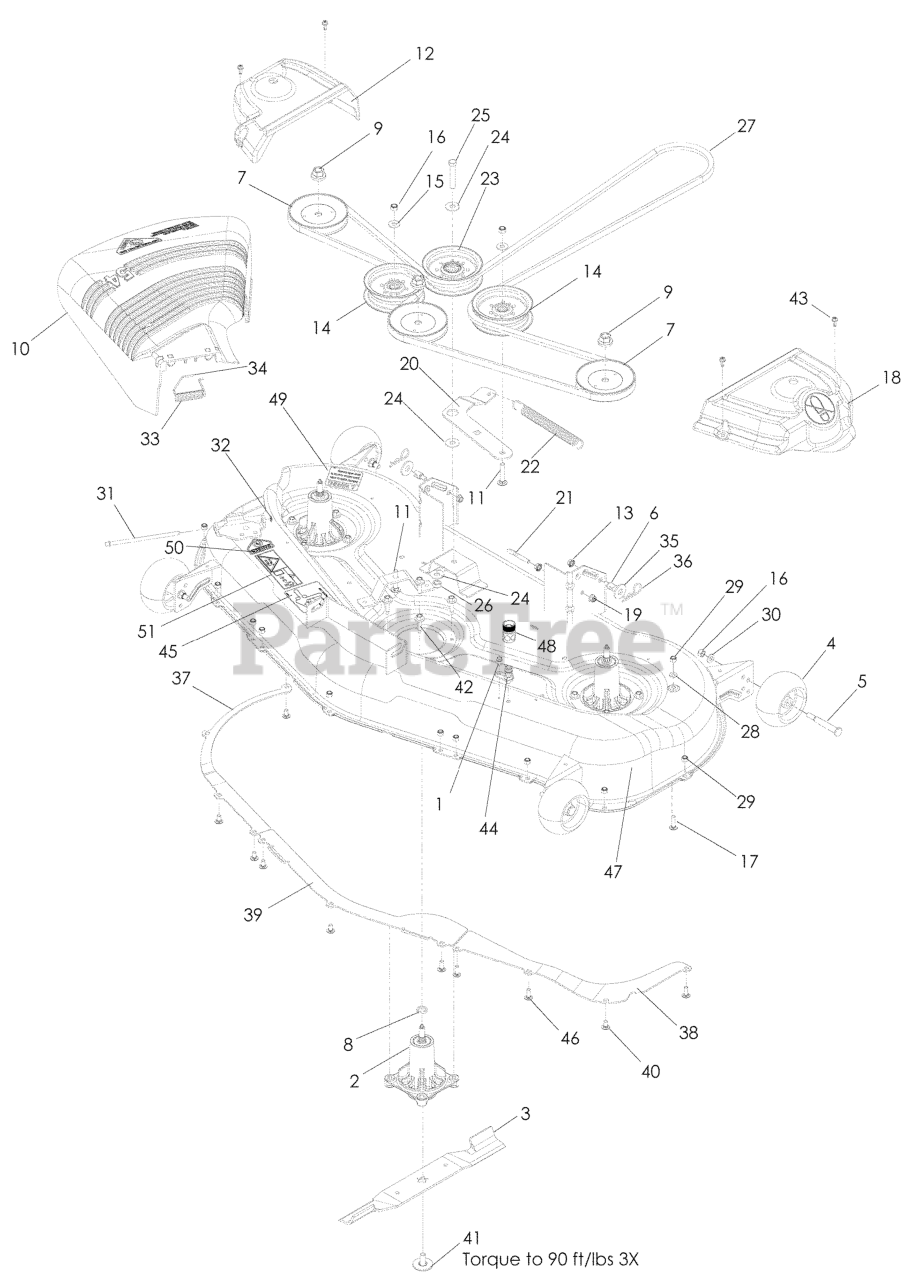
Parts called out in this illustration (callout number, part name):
1	BOLT 1/4-20 X 1/2 HWST
2	MANDREL GREASABLE
3	BLADE, BAGGING 54"
4	GAUGE WHEEL
5	SHOULDER BOLT 1/2X2-5/8 ZD SPE
6	STUD.FASTNER.W/ANTI-ROTATE
7	PULLEY
8	WASHER/SPACER
9	LOCKNUT - 9/16
10	DEFLECTOR, 54"
11	RHSNB 3/8C X 2
12	BELT SHIELD, RT
13	NUT 5/16C WHIZ
14	PULLEY.IDLER.2006
15	WASHER 3/8 FLAT
16	NUT 3/8-16 NYLOC
17	BOLT 5/16C X 3/4" CARRIAGE
18	BELT SHIELD, LT
19	5/16-18 NYLOC FLANGE NUT
20	ARM.IDLER.BLACK
21	EYE BOLT 5/16 X 3.50
22	SPRING, DECK BELT
23	PULLEY.IDLER.MWR.STATI.LH
24	WASHER 7/16 FLAT ZD
25	BOLT 7/16-14 X 2-1/2 GR 5 ZD
26	7/16-14 HEX NUT W/NYL RING ZD
27	BELT.DECK.52".54"
28	FLAT WASHER 5/16 SAE
29	NUT 5/16 NYLOC
30	WASHER 3/8 SAE FLAT
31	ROD, HINGE
32	PUSH NUT
33	TORSION SPRING
34	CAP-SLEEVE
35	WASH USS FLAT 1/2
36	HAIRPIN #4
37	BAFFLE, RIGHT 54"
38	BAFFLE LEFT 54
39	BAFFLE, CENTER, 54"
40	CARRIAGE BOLT 5/16C X 5/8"
41	BLADE BOLT ASSY-7/16" TB REPL
42	WASHER HEAD SCREW
43	SCREW- 1/4-20 X 5/8
44	PORT.WASHOUT
45	DECAL, BELT ROUTING
46	CARRIAGE BOLT 5/16C X 5/8"
47	DECK W/DECALS LSZ54 HUS
48	COUPLING.QUICK CONNECT
49	DECAL, CAUTION
50	DECAL, CPSC
51	DECAL, EURO SEVERING
